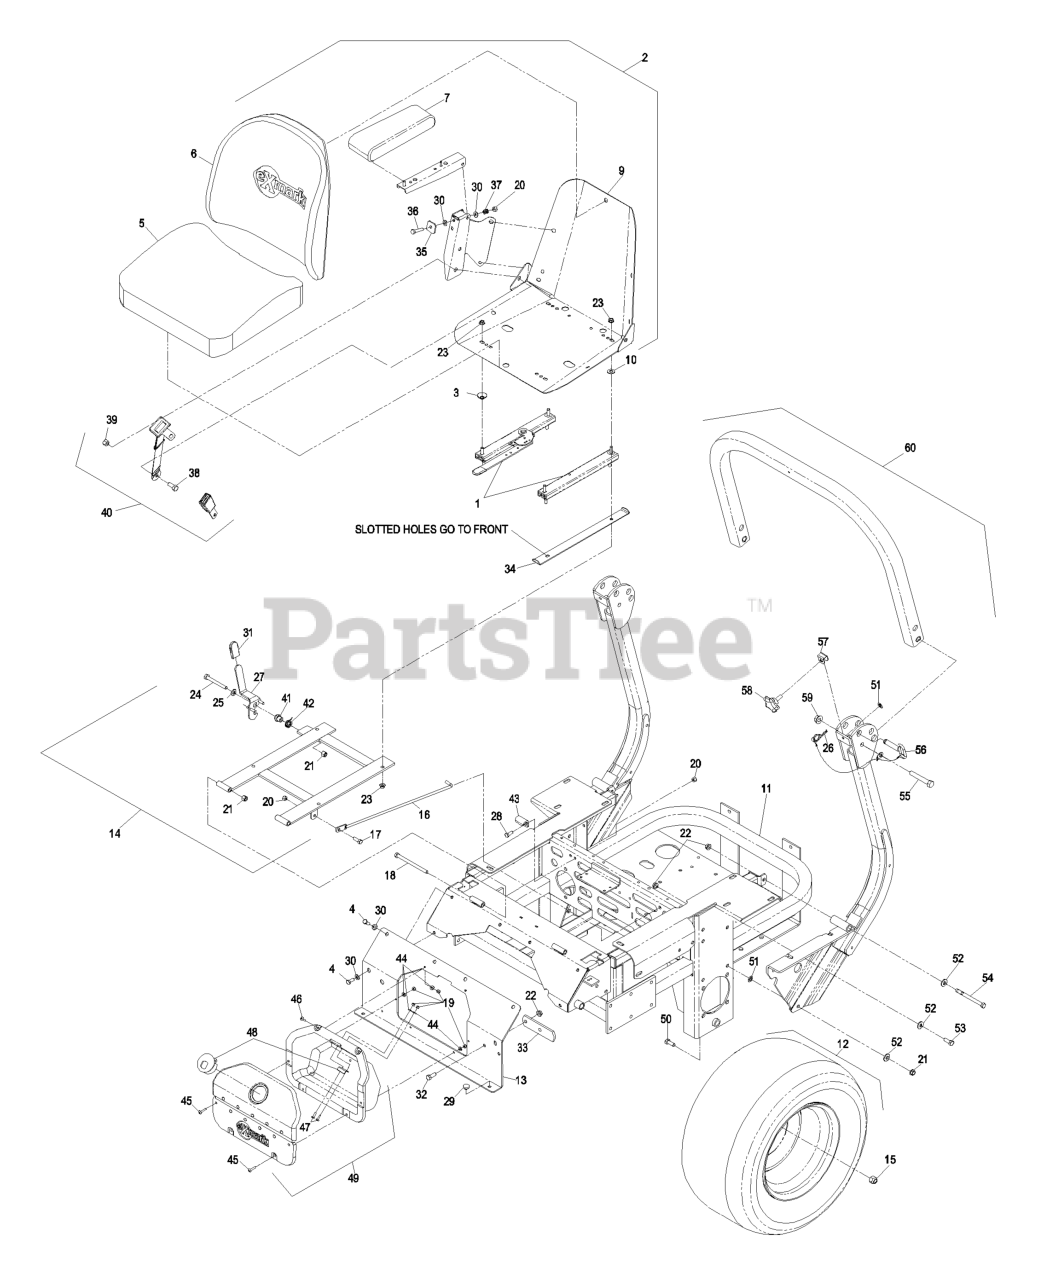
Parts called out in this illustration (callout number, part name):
1	TRACK-SEAT
2	KIT,SEAT W/ARMREST ADJ.
3	SPACER-TRACK
4	SCREW-HH
5	CUSHION,SEAT BOTTOM
6	CUSHION,SEAT BACK
7	CUSHION,ARMREST RH
9	FRAME-SEAT
10	WASHER-FLAT
14	ASM,SEAT FRAME
15	NUT-LUG
16	ROD-HOLDUP, SEAT
17	SCREW-HH
18	SCREW-HH
19	NUT-LOCK, NI
20	NUT-LOCK, NI
21	NUT-LOCK, NI
22	NUT-HHF, WHIZ
24	SCREW-HH
25	WASHER-FLAT
26	HAIRPIN
27	LATCH ASM
28	SCREW-HH
30	WASHER-PLAIN
31	GRIP-LEVER
32	SCREW-HH
33	STOP-BRAKE, PARK
34	STOP-SEAT
35	TAB,ARMREST ADJUSTMENT
36	SCREW-HH
37	SPRING-TANK, FUEL
38	SCREW-HH
39	NUT-LOCK, NI
40	SEATBELT KIT
41	BUSHING-LATCH, SEAT
42	SPRING-TORSION
43	CATCH-LATCH, SEAT
44	WASHER-FLAT
46	SCREW-HEAD, TRUSS
47	SCREW-PPH
48	LATCH,CUBBY
49	ASM,CUBBY
50	SCREW-HH
51	NUT-PUSH
52	WASHER-BELLEVILLE
53	SCREW-HH
54	SCREW-HH
55	SCREW-HH
56	PIN-FOLD, ROPS
60	KIT, LAZER Z 2 POST ROPS
